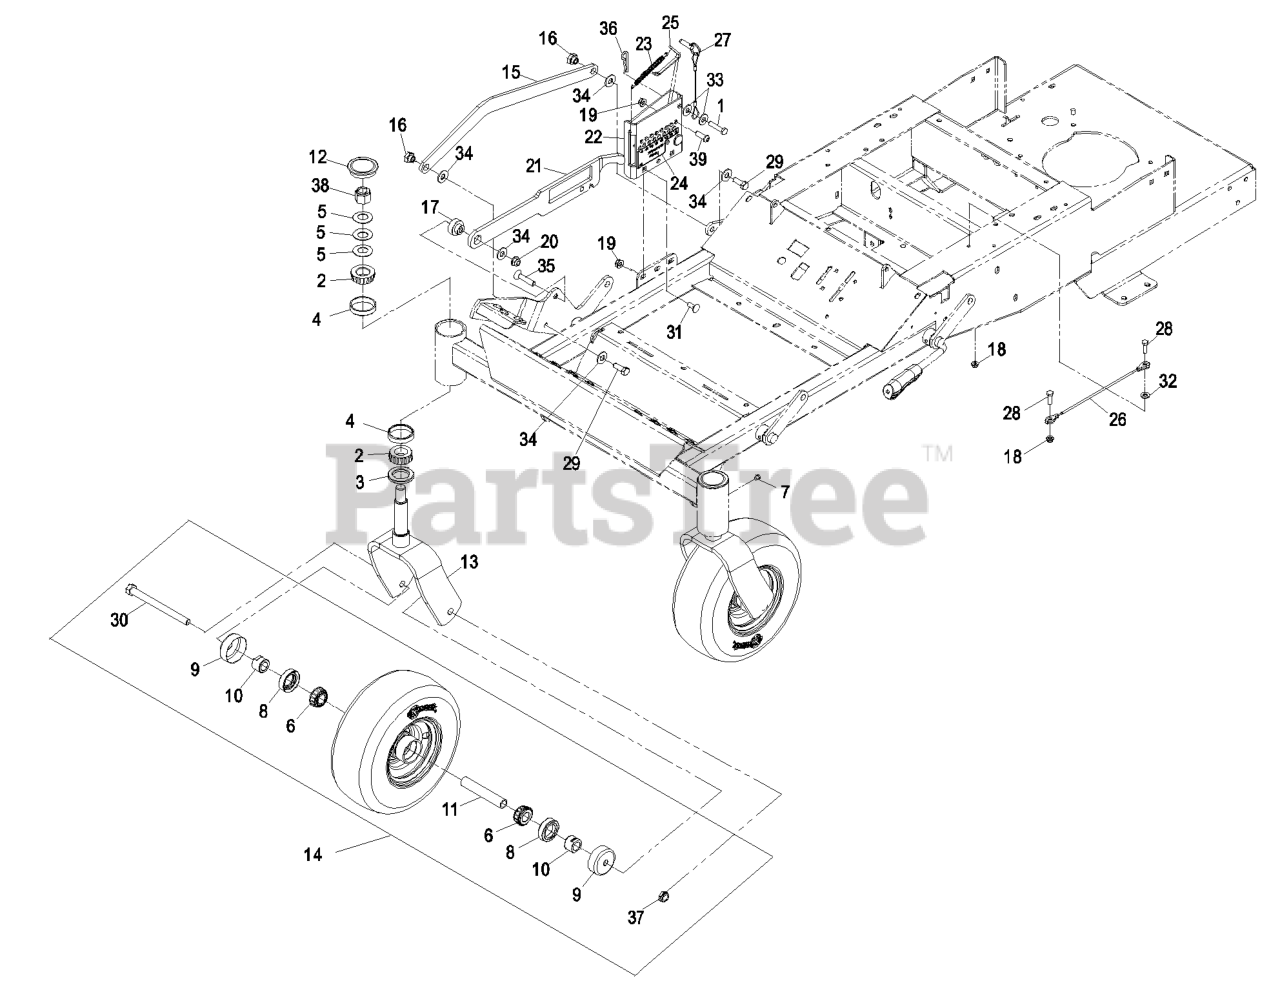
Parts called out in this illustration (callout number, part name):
1	PIN-CLEVIS
2	Cone-Bearing Tapered Roller
3	SEAL-GREASE
4	CUP-BEARING
5	WASHER-BELLVILLE
6	BEARING-CONE, TAPERED ROLLER
8	SEAL-CASTER
9	GUARD-SEAL
10	SPACER-NUT
12	CAP-GREASE
13	FORK-CASTER
14	WHEEL/TIRE AND BEARING AS
15	LINK-CONTROL, DECK
16	NUT-SHOULDER
17	BUSHING
19	NUT-HF, NI
20	NUT-HF, NI
22	HEIGHT ADJUST ASM
23	SPRING-ADJUST, HEIGHT
24	DECAL-HEIGHT, DECK
25	PAWL-CONTROL, HEIGHT
26	CABLE-STOP, SEAT
27	HEIGHT PIN W/LANYARD ASM
28	SCREW-HH
29	SCREW-HH
30	SCREW-HH
31	SCREW-CARR
32	WASHER-PLAIN
33	WASHER-SPRING
35	SCREW-FH
36	PIN-COTTER
37	NUT-HEX
38	NUT-LOCK, NI
39	SCREW-HSBH
